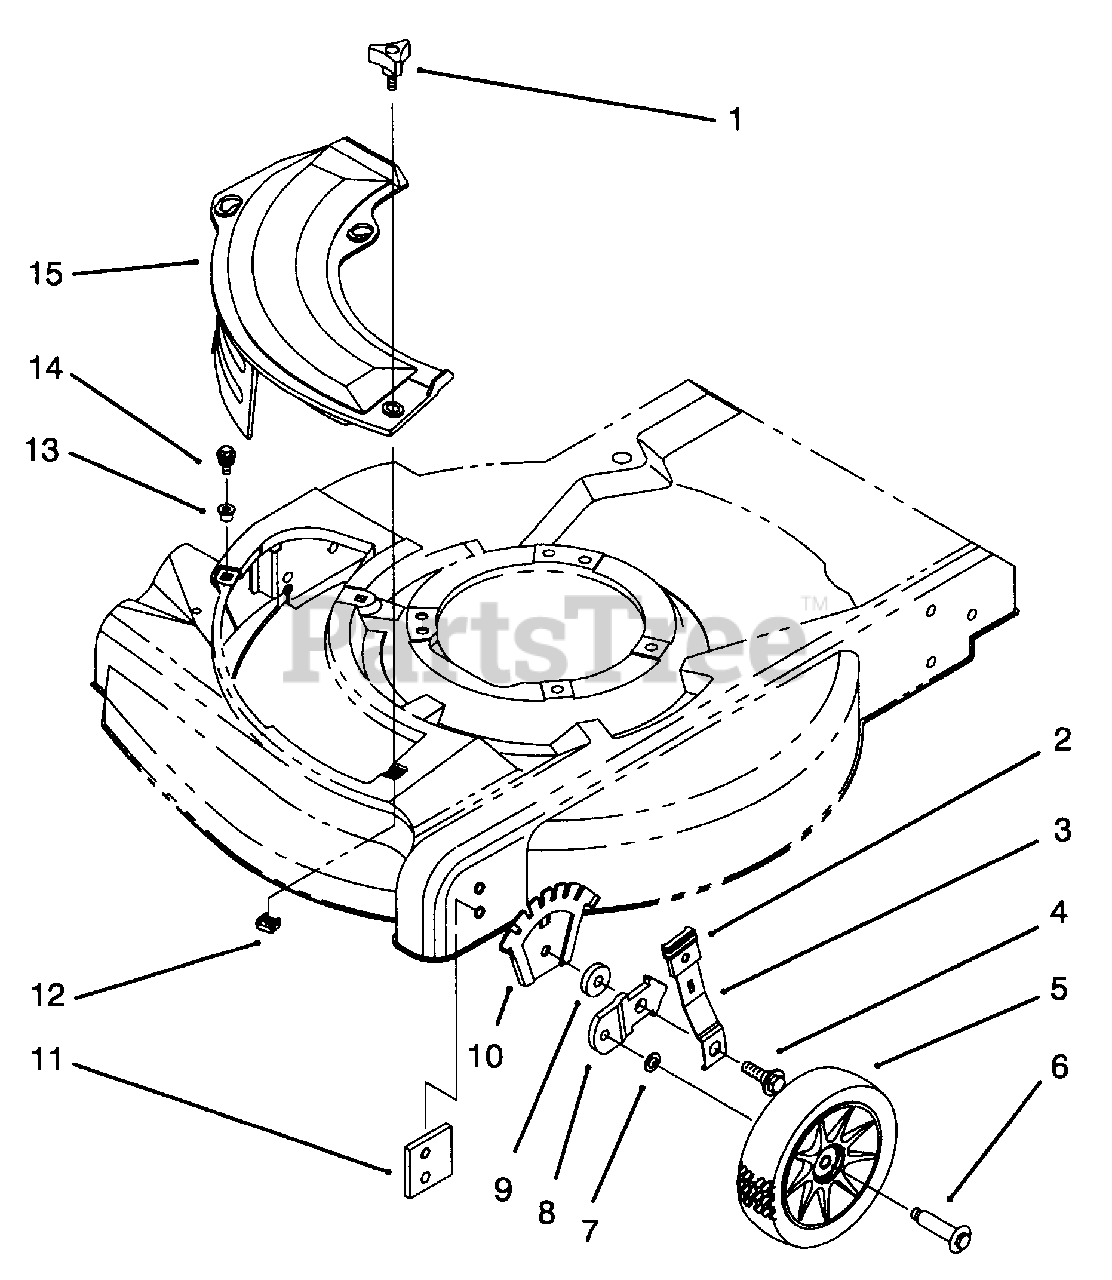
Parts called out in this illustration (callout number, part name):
1	Knob-Cover Plate
2	Knob-Height Adjust
3	Spring Arm Assembly
4	Bolt-Shoulder
5	Wheel & Tire Assembly 6"
6	Bolt-Shoulder
8	Bracket-Wheel Height Adj.
10	Plate-Height Adjust
11	Plate-Baffle
12	Nut-Cage
13	Grommet-Plastic
14	Screw-Sems Thr'd Form.
15	Plate-Mulch
